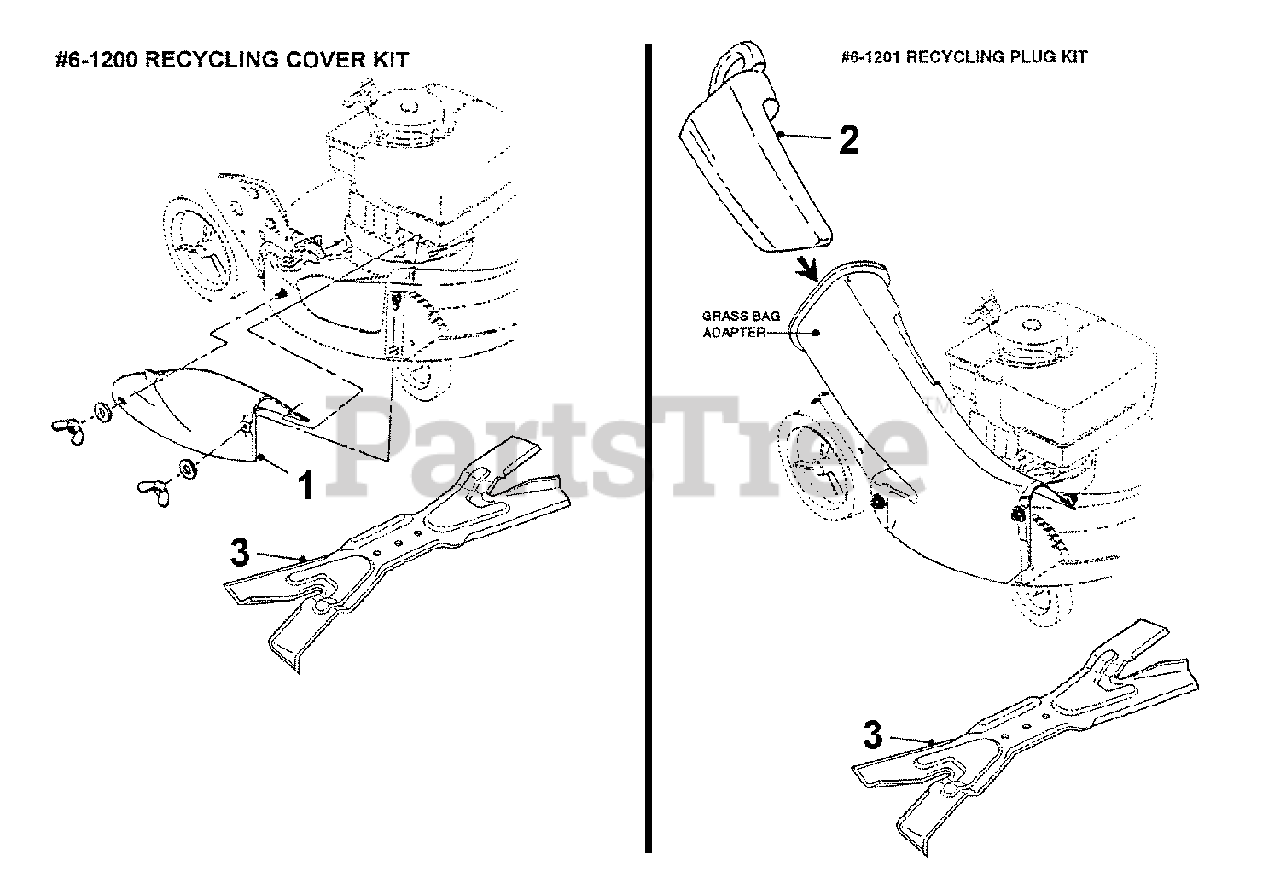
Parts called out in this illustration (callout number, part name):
1	COVER, 21" Deck
2	PLUG, Chute Adapter
3	BLADE, 21" Quad Edge Ninja
